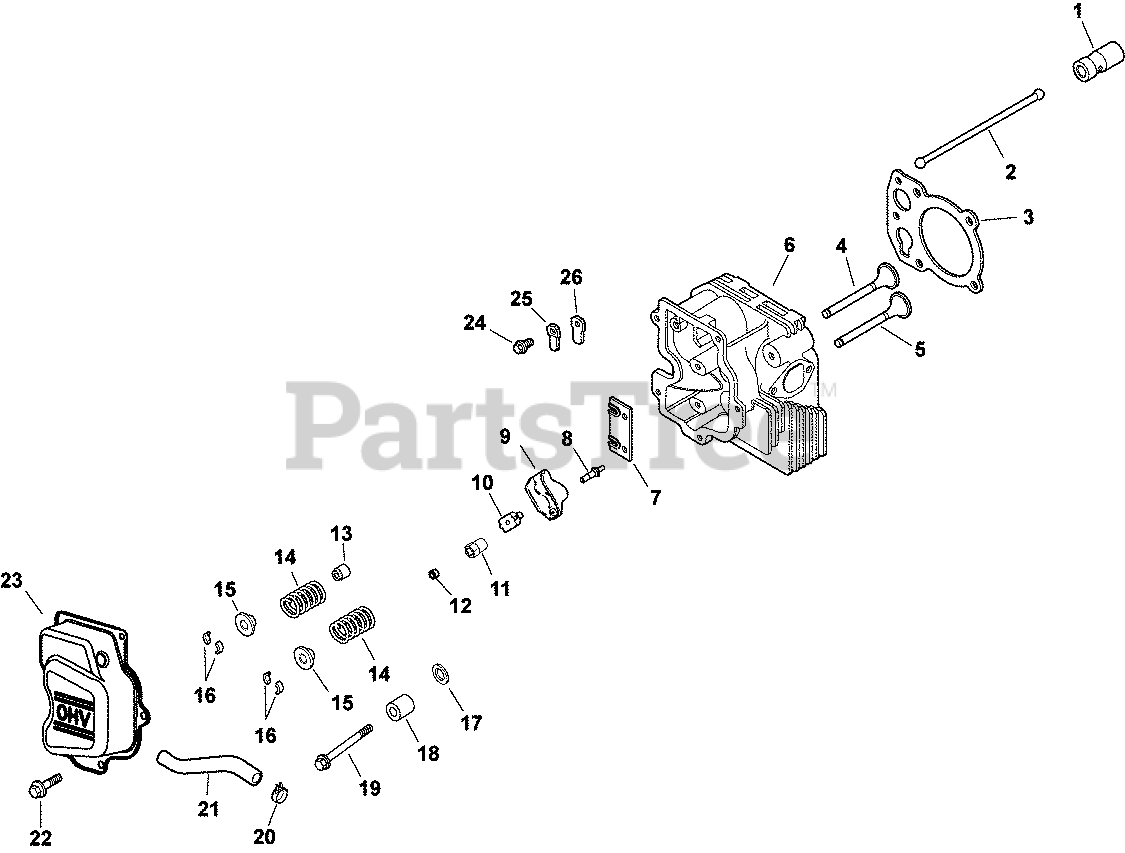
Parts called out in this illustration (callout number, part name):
1	LIFTER, HYDRAULIC VALVE-USE 25 351 10-S
2	ROD, PUSH
3	GASKET, CYLINDER HEAD
4	VALVE, INTAKE
5	VALVE, EXHAUST
6	HEAD ASSEMBLY, CYLINDER
7	PLATE, GUIDE - DISCONTINUED
8	STUD, ROCKER
9	ARM, ROCKER
10	PIVOT, ROCKER ARM
11	NUT, HEX (AVT)-USE 25 100 38-S
12	SCREW, SET (AVT)-USE 25 086 168-S
13	SEAL, VALVE STEM - (#2503214S)
14	SPRING, VALVE
15	RETAINER, VALVE SPRING - USE 25 173 28-S
16	KIT, RETAINER
17	WASHER, FLAT 13/32"
18	SPACER, HEAD BOLT EXHAUST PORT
19	SCREW, CYLINDER HEAD (M10 X 80)
20	CLAMP, HOSE (KM)-USE 25 237 31-S
21	HOSE, BREATHER
22	SCREW,FLG THD FRM M6X1.0X16-(#25086397S)
23	COVER, ROCKER
24	SCREW, FLG THD FRM M5X.8X10
25	RETAINER, REED
26	REED, BREATHER
